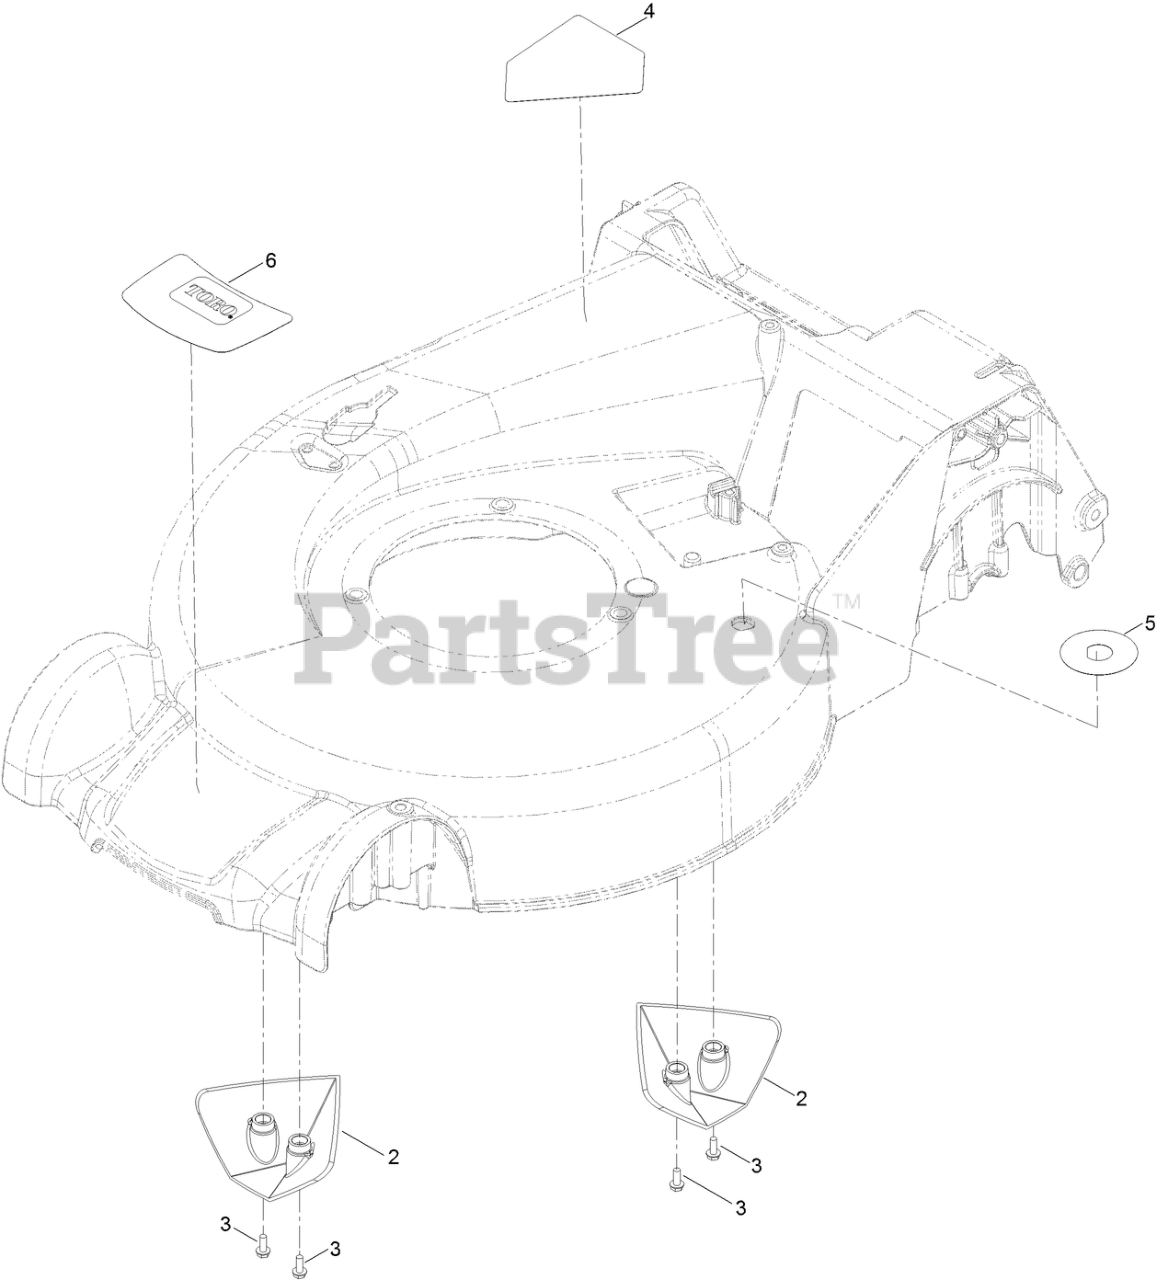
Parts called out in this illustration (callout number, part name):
2	KICKER-FRONT
3	SCREW-TAPTITE
4	DECAL-DANGER
5	DECAL-QUICK WASH
6	DECAL-DECK, SUPER RECYCLER
